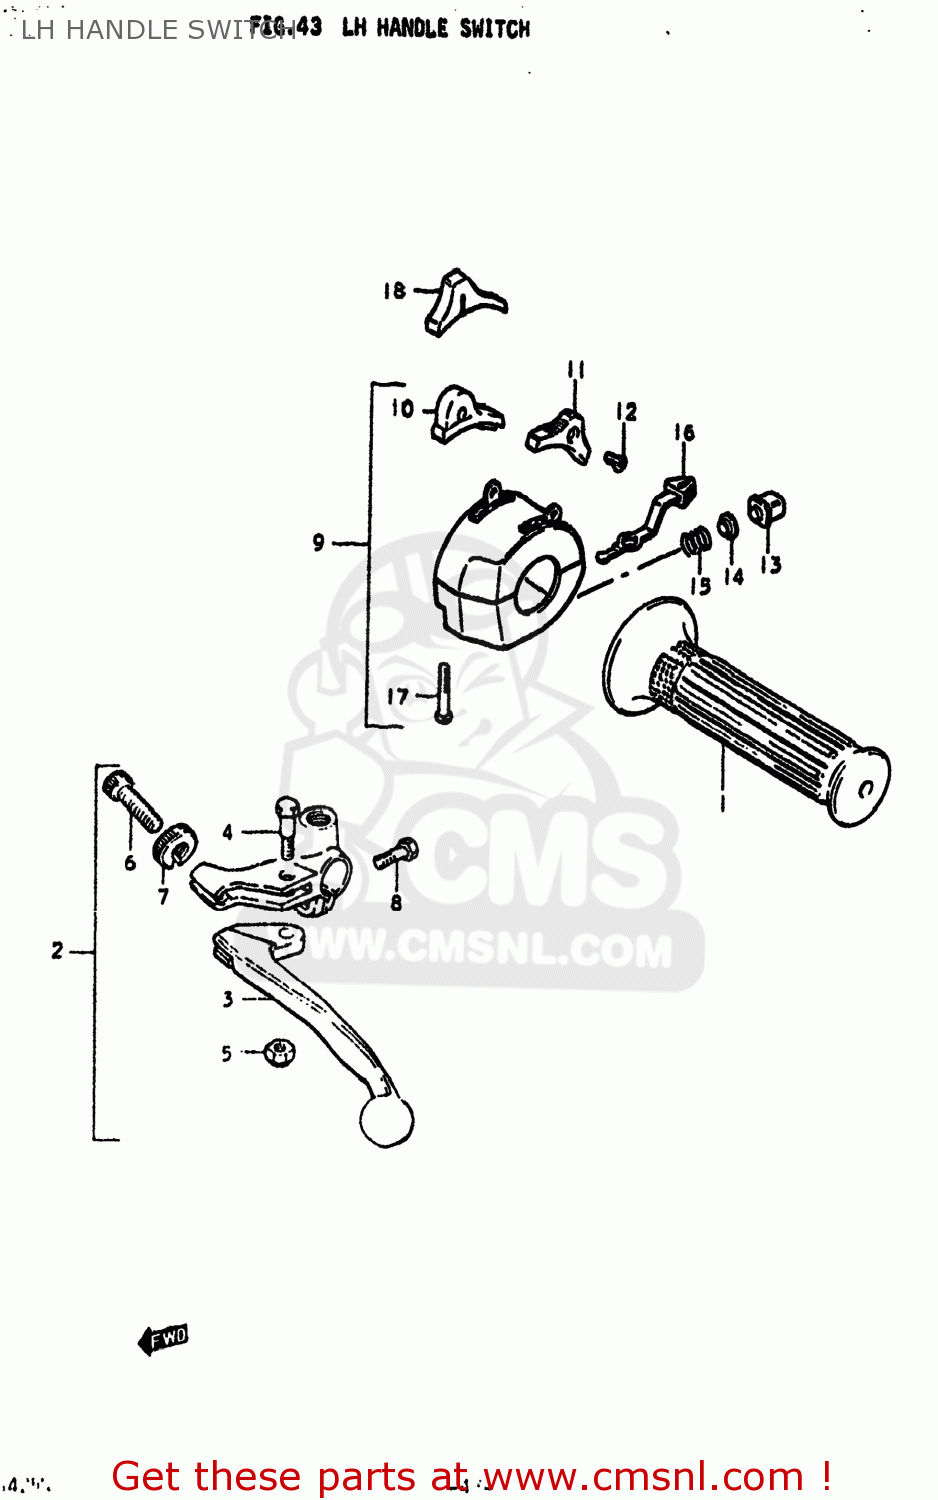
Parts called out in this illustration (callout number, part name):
1	GRIP,LEFT
2	LEVER ASSEMBLY
3	LEVER,CLUTCH
4	BOLT,LEVER
5	NUT 6MM
6	ADJUSTER,CABLE
7	NUT,CABLE ADJUSTER
8	BOLT
9	SWITCH ASSEMBLY,HANDLE,LEFT
10	KNOB,STOP
11	KNOB,DIMMER SWITCH
12	SCREW
13	BUTTON,HORN
14	CONTACT
15	SPRING
16	KNOB,TURNSIGNAL
17	SCREW
18	KNOB,LIGHTING SWITCH
